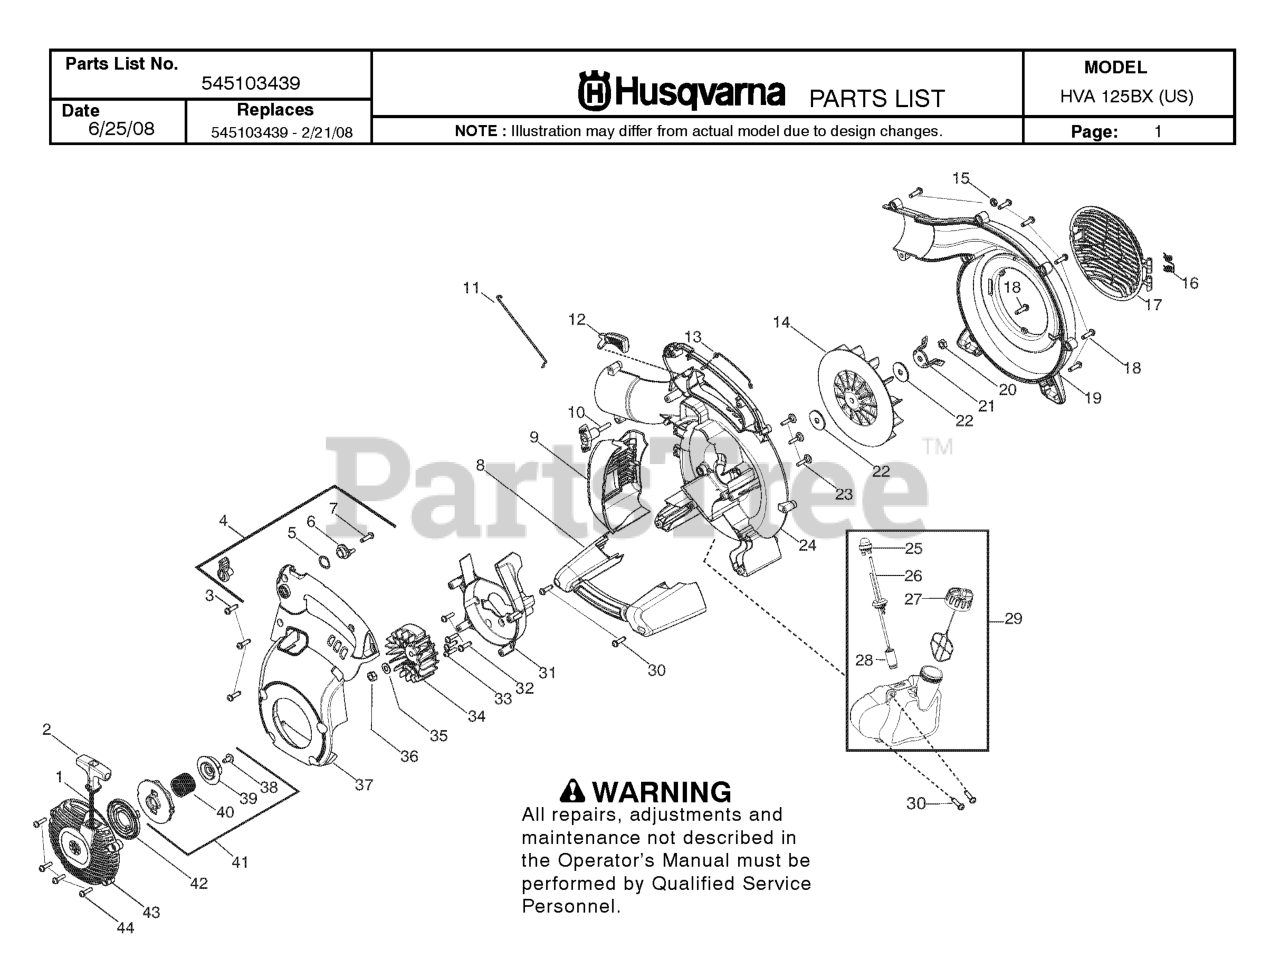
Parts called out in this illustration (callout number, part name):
2	STARTER HANDLE
4	KIT CRUISE CONTROL
5	WAVE WASHER
6	RATCHET CRUISE CONTROL
8	HANDLE ASSIST W/OVER MOLD
9	ASSY, MUFFLER GUARD
10	ASSY, BLOWER KNOB
11	WIRE LINKAGE
12	TRIGGER, THROTTLE
13	WIRE, HANDLE GROUND
14	IMPELLER
16	SPRING, VAC DOOR
17	COVER VAC DOOR
19	ASSY - OUTER SCROLL
20	NUT, IMPELLER
21	BLADE MULCH
22	WASHER IMPELLER
23	SCREW FUEL TANK RETAINER
24	SCROLL - INNER
26	FUEL LINE GROMMET KIT
27	ASSY-CAP W/RETAINER
28	FUEL PICK-UP ASSY
29	ASSY, FUEL TANK
31	SCROLL, FLYWHEEL
33	SCREW - SHROUD
34	ASSY, FLYWHEEL
35	WASHER FLAT
36	NUT-FLYWHEEL
37	COVER - MOTOR HOUSING
40	SPRING EPS2
41	KIT - STARTER
42	SPRING STARTER
43	HOUSING - STARTER COVER
44	SCREW - SHROUD
